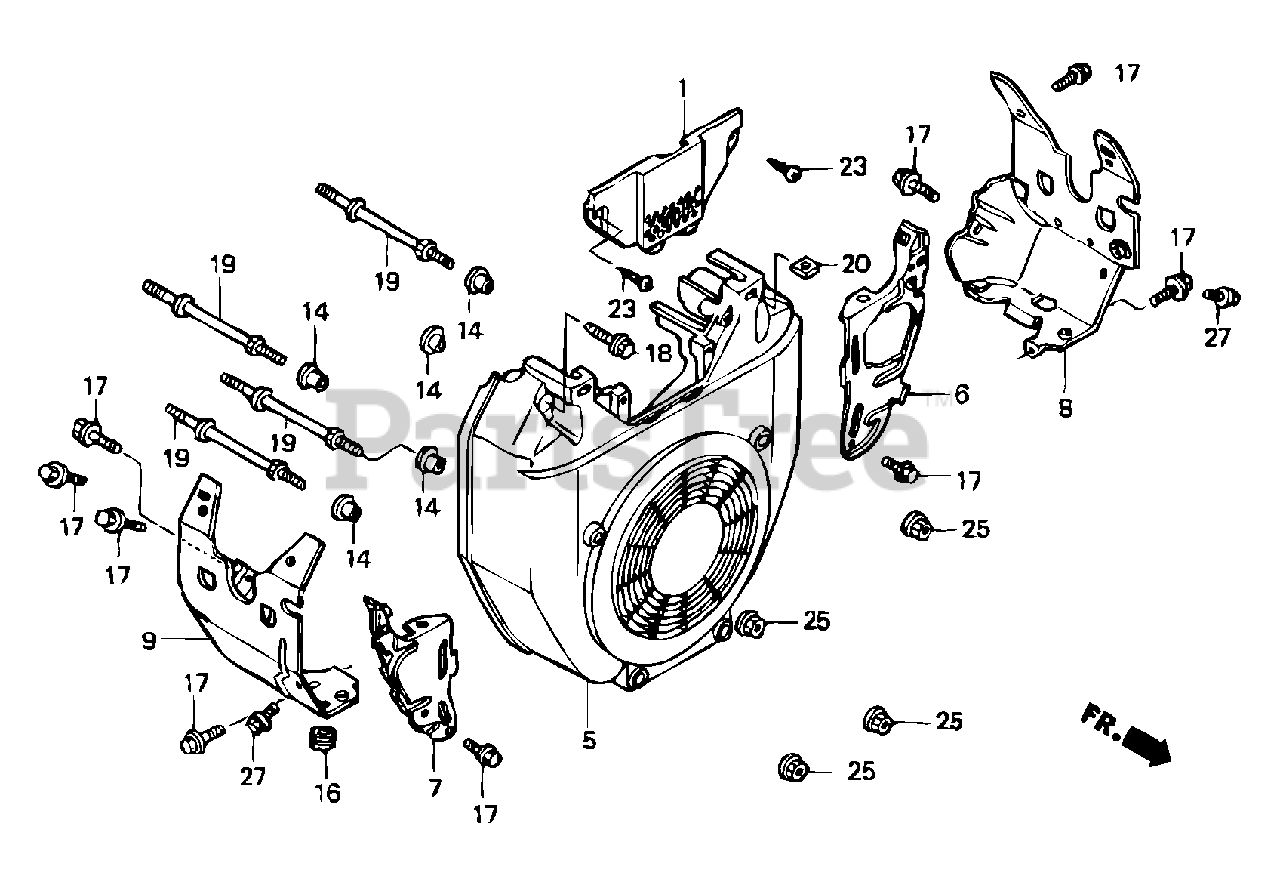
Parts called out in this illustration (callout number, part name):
1	Cover, Fuel Pump
5	Cover, Fan (Bright Red)
6	Plate, R. Side
7	Plate, L. Side
9	Shroud, L
14	Collar B, Taillight
16	Rubber, Rr. Fender Cushion
17	Bolt, Flange (6x12) (Ct200)
18	Bolt, Flange (6x23)
19	Bolt, Stud (6x71)
20	Nut, Square (5mm)
23	Screw, Tapping (5x20)
25	Nut, Flange (6mm)
27	Bolt, Flange (6x8)
